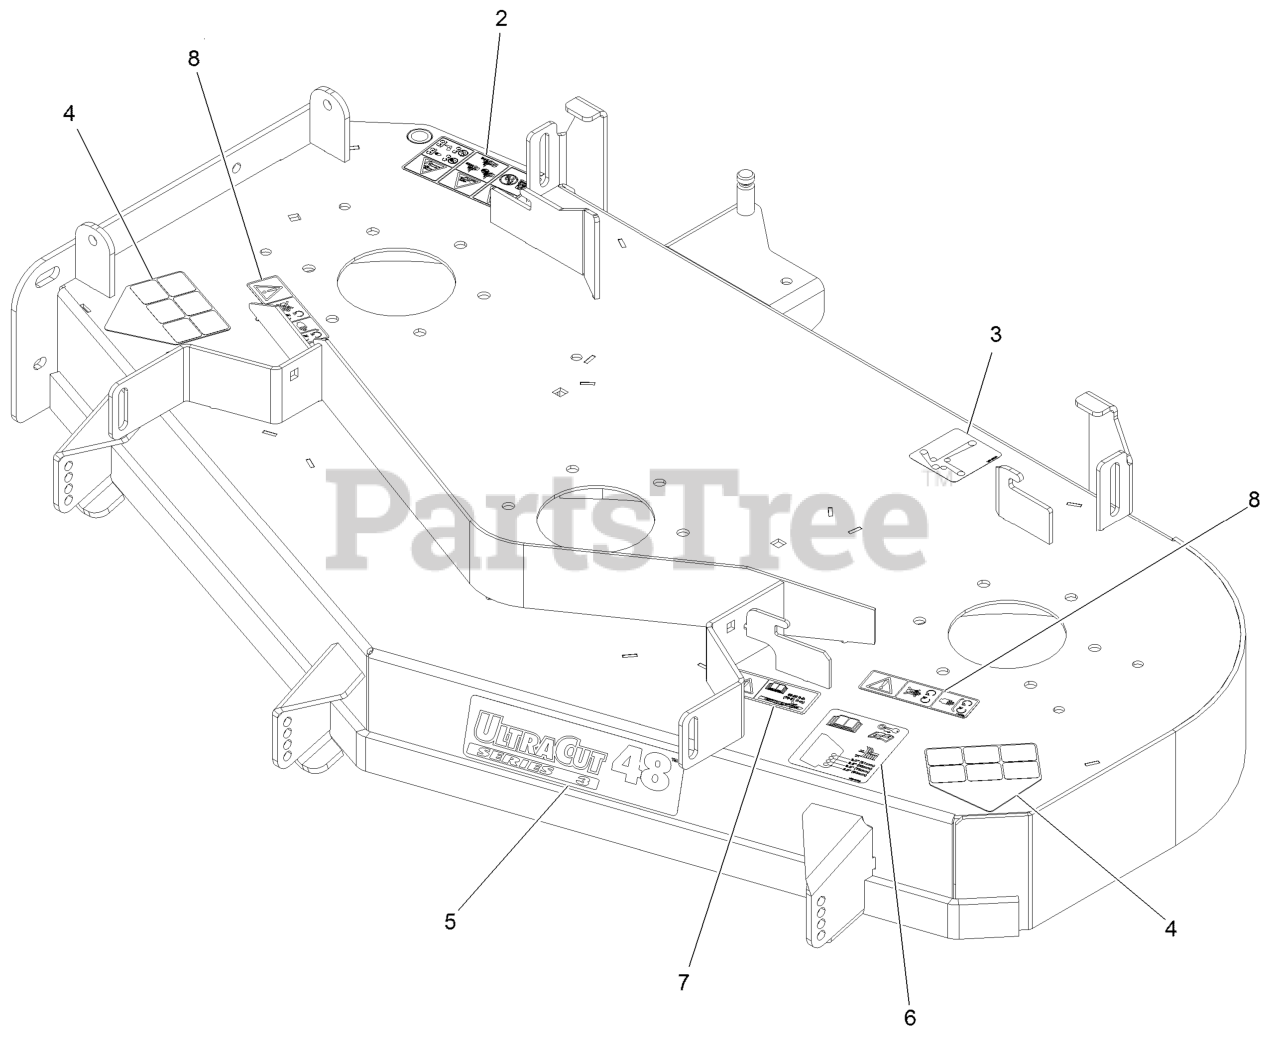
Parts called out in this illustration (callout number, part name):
2	DECAL-DANGER
3	DECAL-ROUTING, BELT
4	DECAL-DANGER
5	DECAL-ULTRACUT 48 SERIES
6	DECAL-ROLLER, ANTI-SCALP
7	DECAL-BOLT TORQUE
8	DECAL-COVER, MISSING
